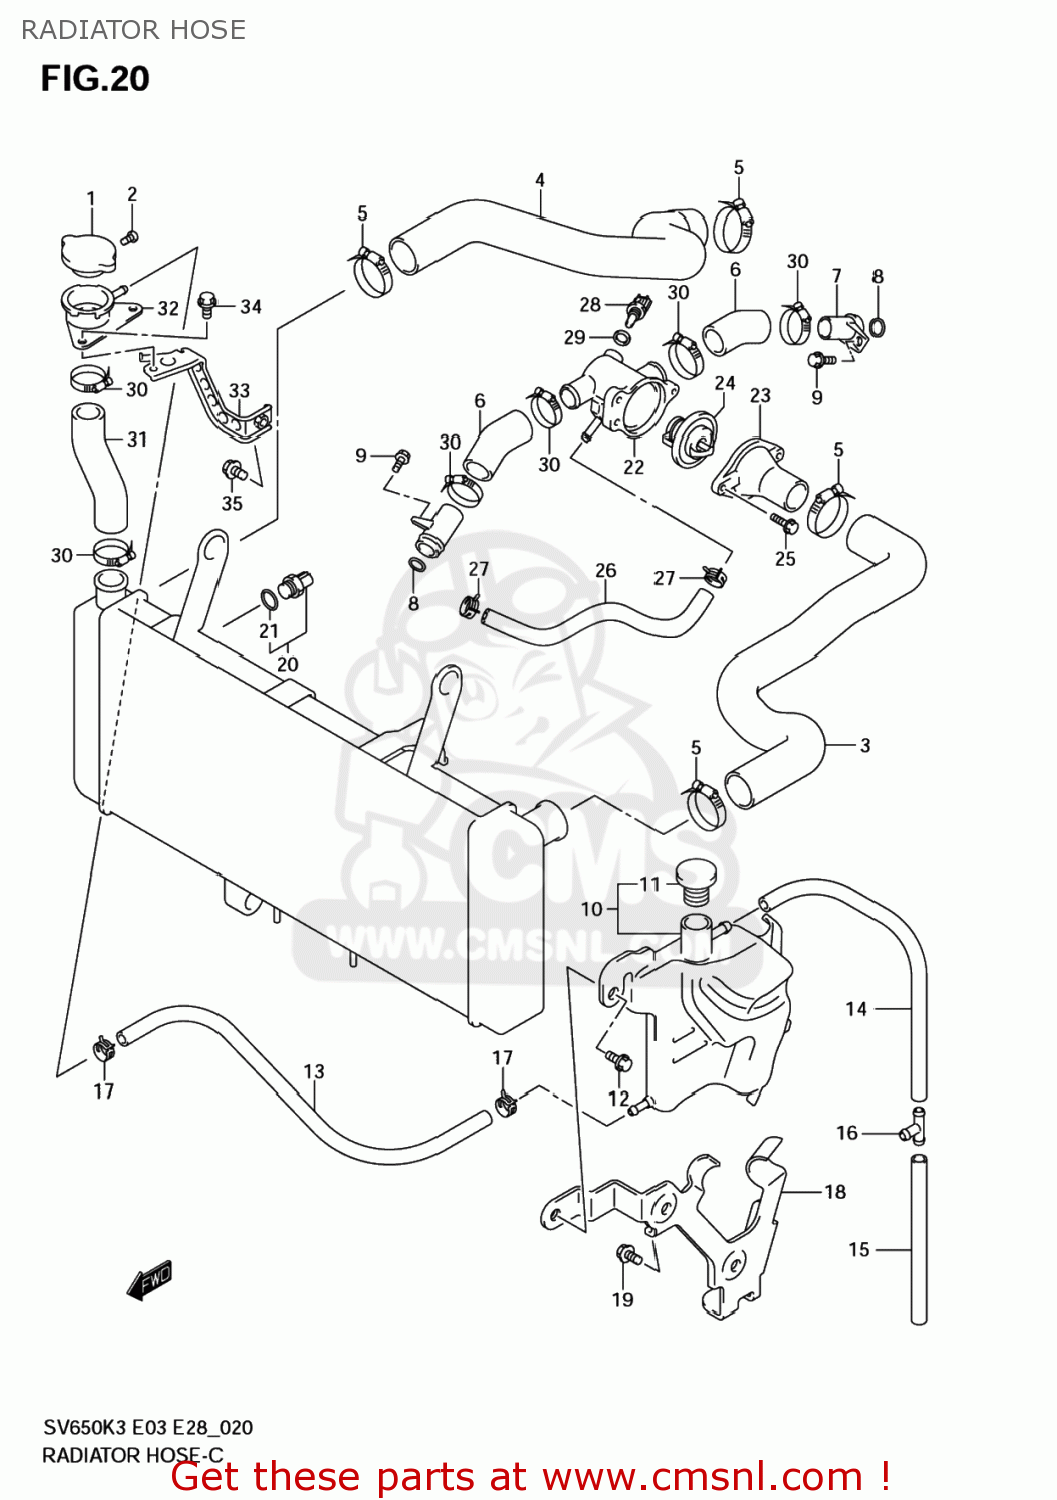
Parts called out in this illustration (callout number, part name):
1	CAP,RADIATOR(1.1)
2	SCREW,RADIATOR CAP
3	HOSE,RADIATOR INLET
4	HOSE,RADIATOR OUTLET
5	CLAMP
6	HOSE,CONNECTOR INLET
7	UNION,CONN HOS
8	O RING(D:3.2,ID:17.8)
9	BOLT,STRANGER
10	TANK ASSY,RESERVOIR
11	CAP,RESERVOIR TANK
12	BOLT(6X12)
13	HOSE(5X9X600)
14	HOSE(5X9X600)
15	HOSE(7X10.2X600)
16	3 WAY
17	CLIP
18	BRACKET,RESERVOIR TANK
19	BOLT
20	SWITCH,FAN THERMO
21	O-RING
22	CONNECTOR,THERMOSTAT INLET
23	CAP,THERMOSTAT CONNECTOR
24	THERMOSTAT,WATER
25	BOLT
26	HOSE,CONNECTOR TO WATER PUMP
27	CLAMP
28	SENSOR,WATER TEMP
29	GASKET(12X17X1) (NAS)
30	CLAMP
31	HOSE,CONDUCTION
32	CONDUCTION,RADIATOR
33	BRACKET,CONDUCTION
34	BOLT
35	BOLT
